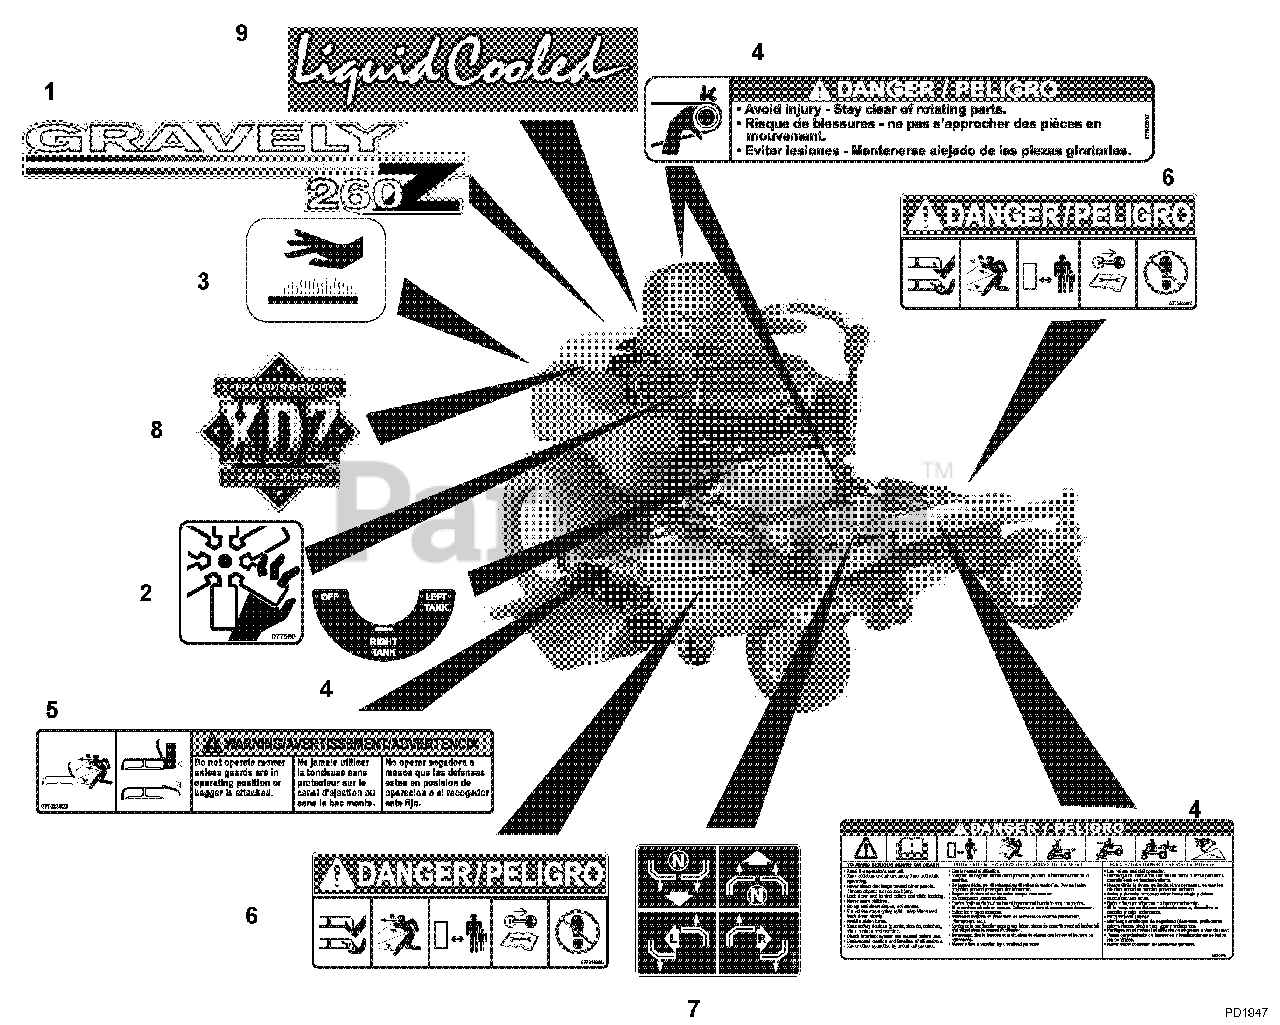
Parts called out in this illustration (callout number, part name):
1	Decal, PM-252Z Hood (992146, 148, 149, 150)
2	Decal, Danger Fan
3	Decal-Hot Surface
4	Set, Decal-Common Danger/Fuel
5	Decal, Warning
6	Decal, Mower Pan Head Danger
7	Decal-Instructional
8	Decal, XDZ (992148, 149, 150, 151, 152, 153, 154, 155, 157, 159)
9	Decal, Liquid Cooled (992152, 157, 159)
